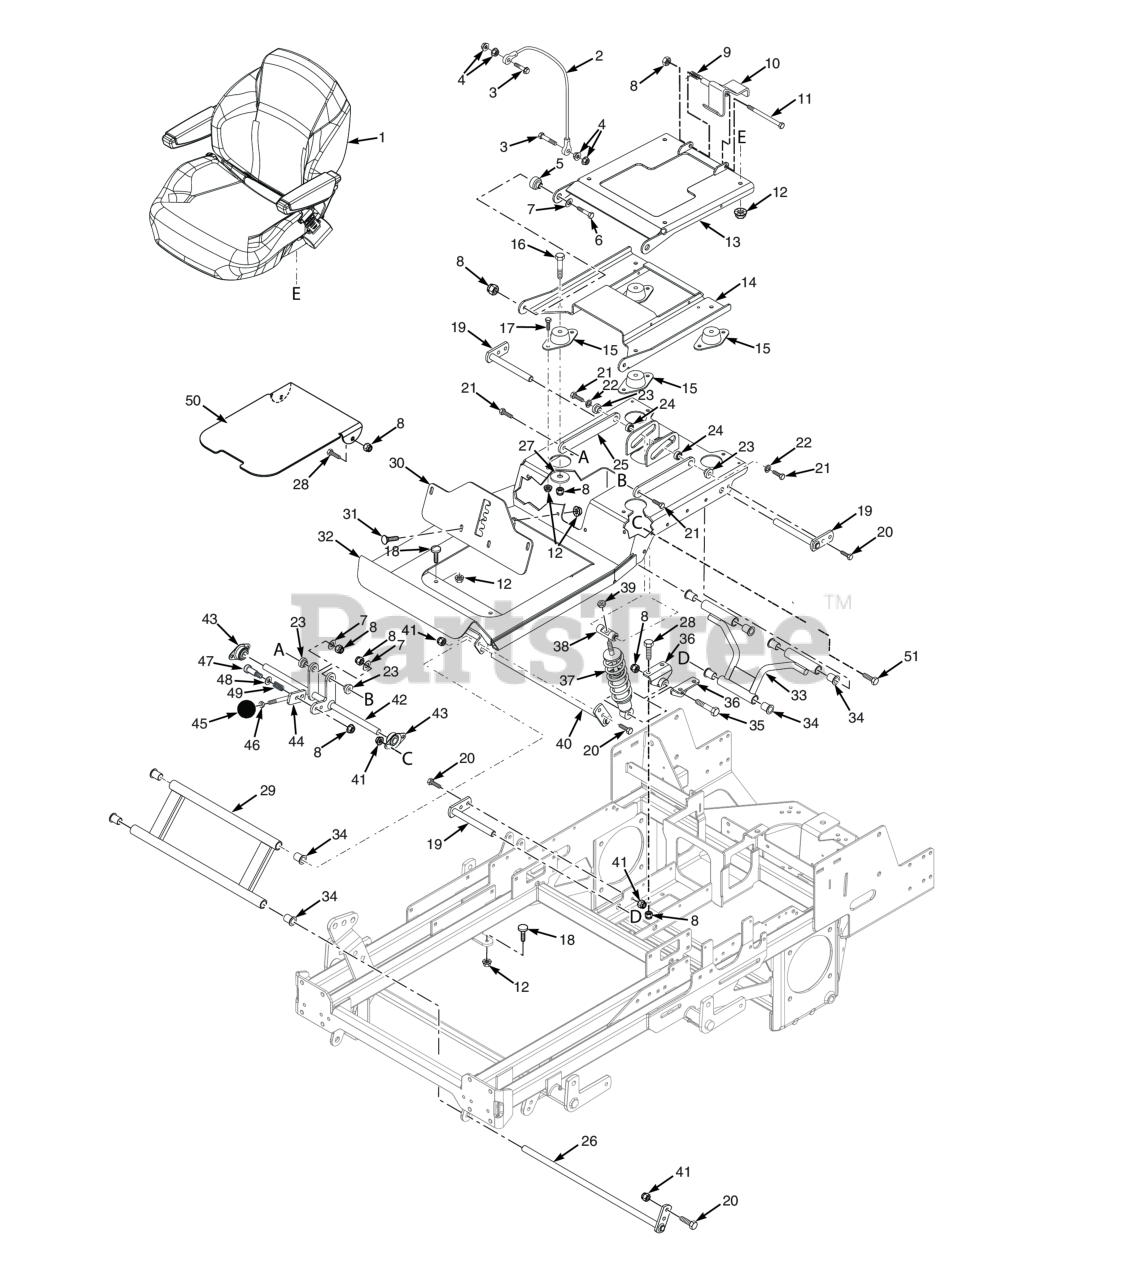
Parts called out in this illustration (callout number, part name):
1	Seat Assembly (INCL 14)
2	Cable, Seat Stop
3	SERR. FLG. HEX HEAD CAPSCREW, 5/16-18 X 3/4
4	NUT, 1/4-20 SERRATED FLANGE HEX HEAD
5	Sleeve, Seat Base Mounting
6	Capscrew, Hex Head 3/8-16 x 2.0"
7	Flatwasher, 3/8" Special (.391 x .938 x .105)
8	HEX NUT, ELASTIC STOP LOCK, 3/8-16
9	Spring, Seat Latch
10	Latch Weldment, Seat
11	Bolt, 3/8-16 x 6.00" Hex Head
12	Nut, Serrated Flange 5/16-18 (Right Front Engine Mounting, Briggs and Kohler Only)
13	Seat Plate Weldment
14	Seat Mounting Plate Weldment w/Decal
15	Isolator, Seat
16	Bolt, Hex Head 3/8-16 x 2-1/4" - 61"
17	BOLT, SERRATED FLANGE HEX HEAD 5/16-18 X 3/4"
18	Bumper, Rubber
19	Shaft Weldment, Rear Op. Platform Pivot
20	Bolt, Heax Head 5/16-18 x 1" (48V / 52V)
21	Bolt, Hex Head, 3/8-16 x 1-1/2"
22	Lockwasher, 3/8" Spring, Kawasaki FX / FS
23	BUSHING, SPEED ADJUSTMENT LEVER
24	Bearing
25	Link, Suspension Seat Tensioner
26	Pin Weldment, Op Platform Lower Pivot
27	Flatwasher, 3/8-.406 x 2.25" x .1875
28	Bolt, Hex Head, 3/8-16 x 1 Gr. 5
29	Suspension Pivot Assembly, Front
30	Bracket, Suspension Adjustment w/Decal
31	Bolt, Carriage 5/16-18x1" (large frame units only)
32	Seat Mounting Base Weldment w/Decal
33	Suspension Pivot Assembly, Rear
34	Bearing, .625 ID Plastic
35	Capscrew, Hex Head 3/8-16 x 2.75"
36	Mount Weldment, Shock
37	Shock Absorber, Suspension
38	Mount, Suspension Shock
39	Nut, Elastic Stop 3/8-16, grade 8 black
40	Pin Weldment, Op Platform Upper Pivot
41	HEX NUT, ELASTIC STOP LOCK, 5/16-18
42	Pivot Weldment, Suspension Tensioner
43	Bearing, Self Aligning - 5/8 I.D.
44	Adjustment Lever, Suspension
45	Knob, OCDC Lever
46	HEX NUT, JAM 3/8-16
47	Bolt, Shoulder 3/8 x 1"
48	Flatwasher, 3/8 (.406 x .812 x .065)
49	Spring, Speed Control Slide
50	Cover, Foot Plate
51	BOLT, SERRATED FLANGE HEX HEAD 5/16-18 X 3/4"
